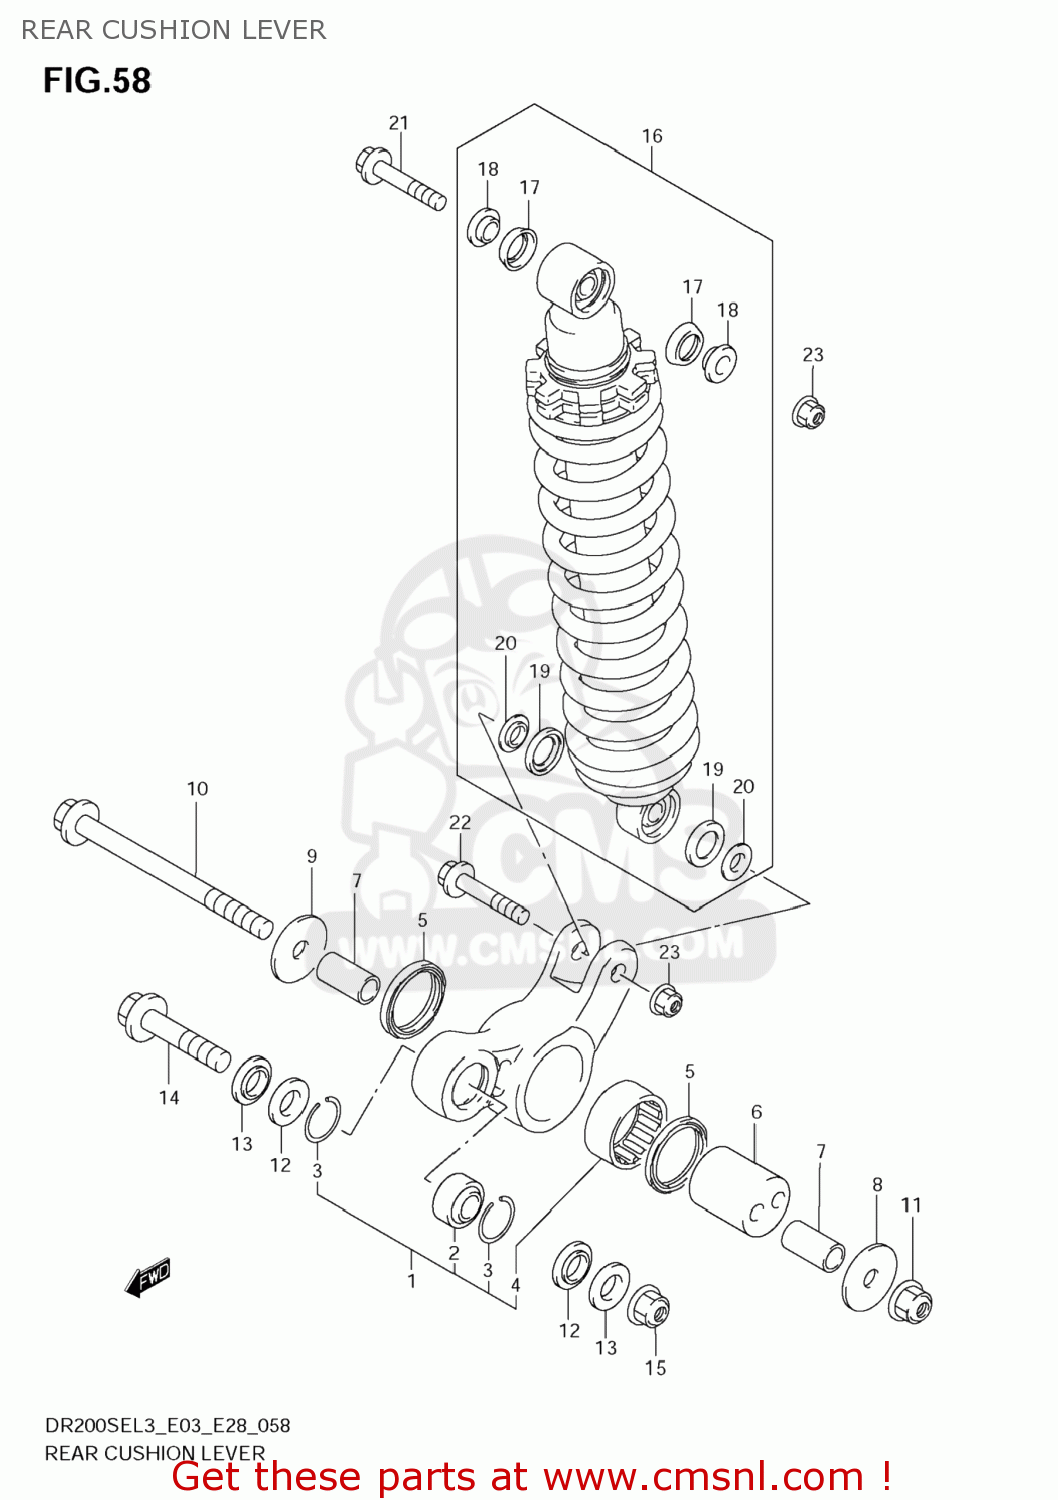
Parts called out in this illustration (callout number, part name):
1	LEVER SET,RR CUSHION
2	BEARING(12X26X16)
3	RING,BEARING STOPPER
4	BEARING(37X47X20)
5	SEAL,DUST
6	SPACER,RR SUSPENSION ECCENTRIC
7	SPACER,CUSHION LEVER SHAFT
8	WASHER,RR CUSH LVR CTR,L
9	WASHER,RR CUSH LVR CTR,R
10	SHAFT,RR CUSHION LEVER CTR
11	NUT
12	SEAL,RR CUSHION ROD DUST
13	SPACER,RR CUSHION ROD
14	BOLT,CUSHION LEVER FR
15	NUT
16	ABSORBER ASSY,RR SHOCK
17	DUST SEAL
18	SPACER
19	DUST SEAL,RR SHOCK
20	COLLAR
21	BOLT(10X58)
22	BOLT(10X48)
23	NUT
